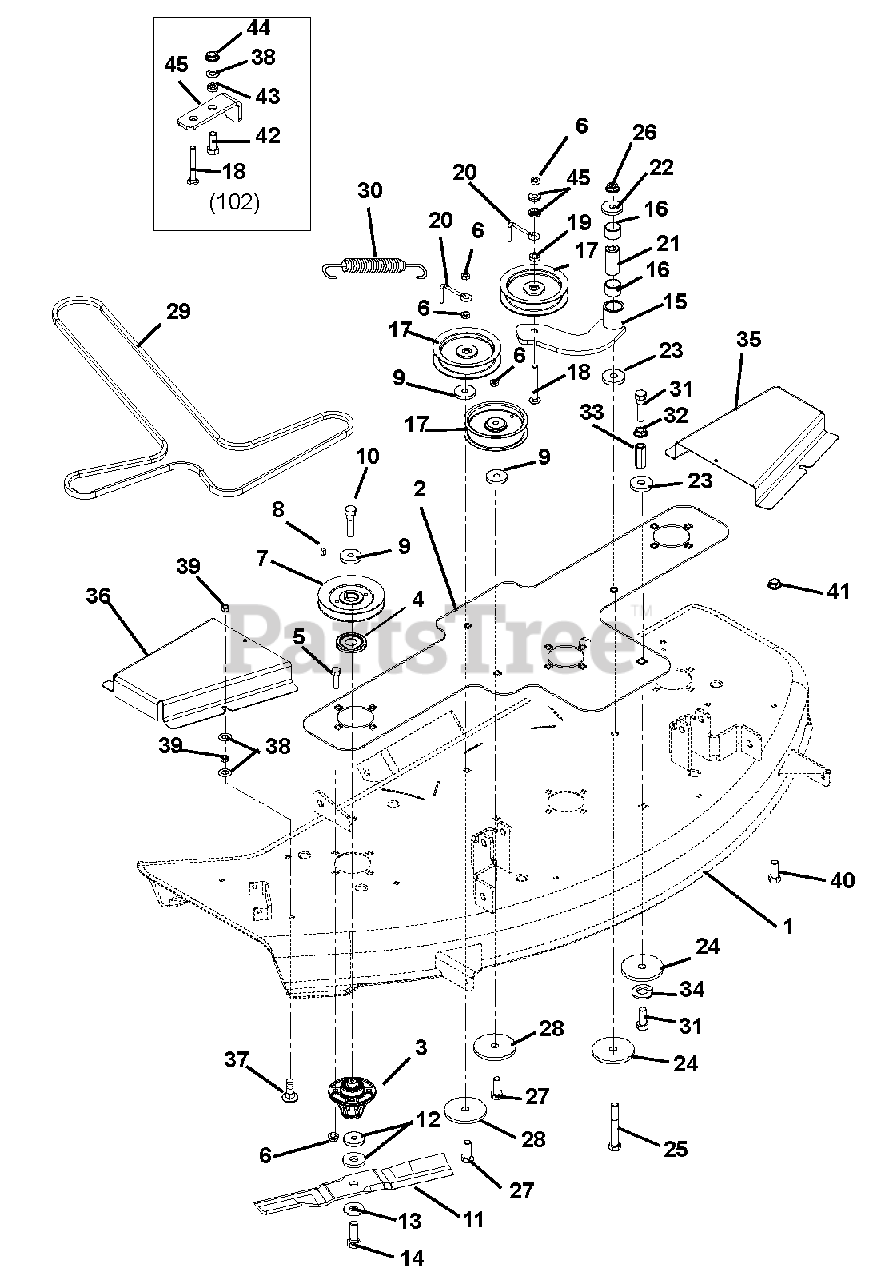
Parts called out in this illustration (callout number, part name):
1	Weldment 50" Deck (104, 106, 116)
2	Deck Doubler, (104, 106, 116)
3	Spindle Assembly
4	Dust Cap
5	Bolt, Round Head Square Neck .38-16 x 1.25
6	Nut .38-16 Flange Nyloc (104, 106, 116)
7	Sheave, Spindle 4.75 Dia. (104, 106, 116)
8	Key, Square .25 x .38 x .25
9	Washer, Flat Steel .406 x 1.50 x .245
10	Bolt, Hex .38-16 x 1.00 EP30 Grade 8
11	Blade, Mower (104, 106, 116)
12	Washer, Flat .640 x 1.81 x .250
13	Washer, Beveled .63 x 1.625 x .140
14	Bolt, Hex .62-18 x 1.75 Grade 8
15	Weldment, Idler Arm
16	Bearing, 1.00 x 1.12 x .75
17	Idler, Flat .38 x 4.00 x 1.06
18	Bolt, Round Head Square Neck .38-16 x 3.50 Grade 5 (104, 106, 116)
20	Finger, Belt (104, 106, 116)
21	Spacer, Powdered Metal
22	Washer, Flat Steel .511 x 1.44 x 125
23	Washer, Flat Steel .515 x 1.625 x .25
24	Washer, Flat Steel .531 x 3.00 x .25
25	Bolt, Hex .50-13 x 3.50 Grade 5
26	Nut, Locking-Top-Flange .50 - 13
27	Bolt, Hex .38-16 x 2.75 Grade 5
28	Washer, Flat Steel .469 x 2.00 x .25
29	V-Belt, HA x 140.2 EFF. (104, 106, 116)
31	Bolt, Hex .50-13 x 1.25 Grade 5
32	Nut, Spin Lock Flange .50-13
33	Nut, Coupling .50-13 x 1.75
34	Washer, Lock 1/2
35	Belt Cover, Left (104, 106, 116)
36	Belt Cover, Right (104, 106, 116)
37	Bolt, Round Head Square Neck .31-18 x 1.25 Grade 5
38	Washer, Flat Steel .38 x .875 x .083 (104, 106, 116)
39	Nut, .31-18 Nyloc Flange
40	Bolt, Hex .31-18 x .75 Grade 5 (104, 106, 116)
41	Nut, Spin Lock-Flange .312-18 (104, 106, 116)
42	Bolt, Hex .38-16 x 1.00 Grade 5 (102)
43	Bushing-Sleeve .377 x .624 x .235 (102)
44	Nut, Locking-Top-Flange .38-16 (102)
45	Belt Finger (102)
